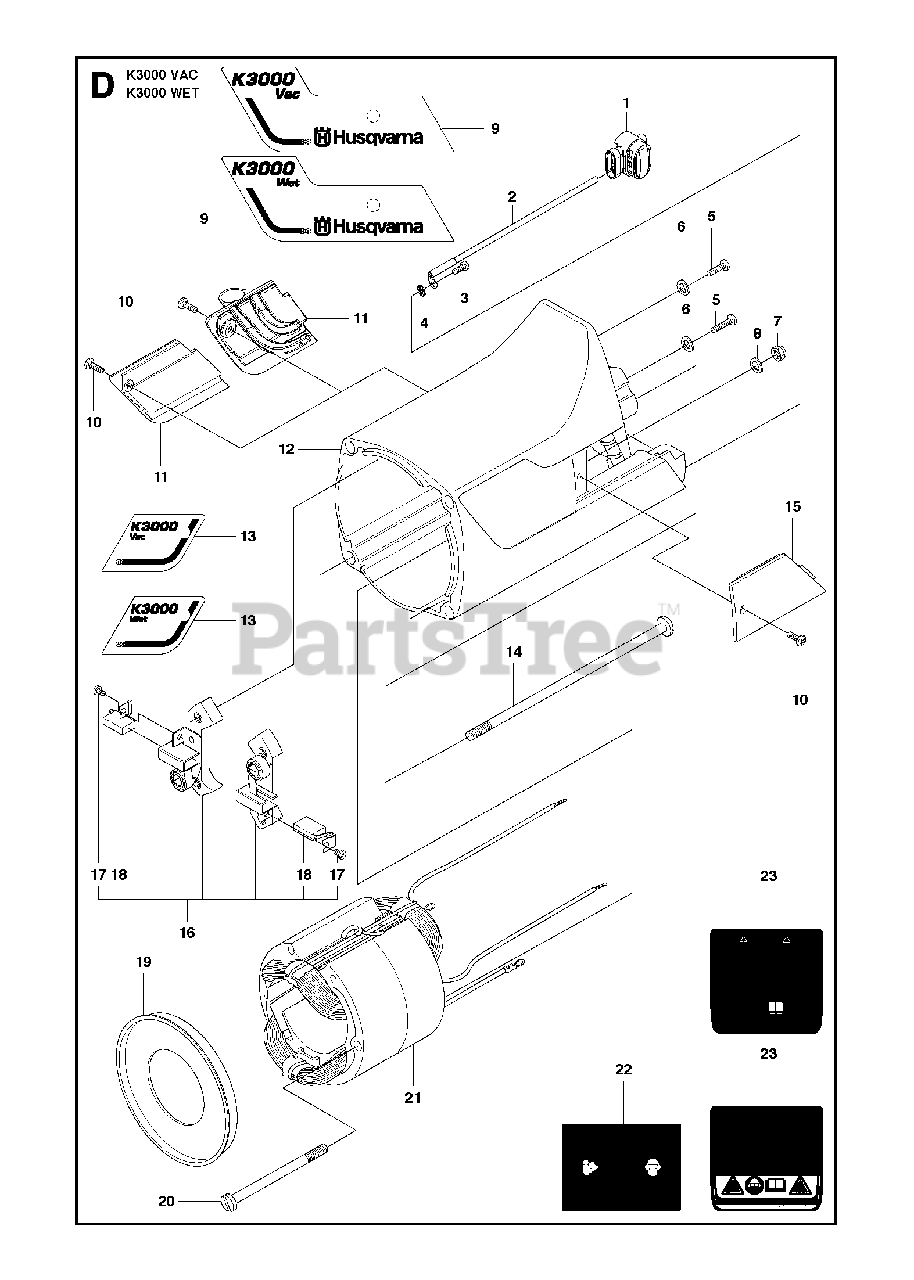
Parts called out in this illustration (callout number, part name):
1	COUPLER
3	SCREW CRPANM
6	SPRING WASHER
8	SPRING WASHER
10	SCREW CRPANT
16	BRUSH HOLDERIncl. 17 - 18
18	CARBON BRUSH
19	AIR STREAM DIRECTOR
21	STATOR ASSY100 - 120V
21	STATOR ASSY230V
23	LABELUSA, UK
